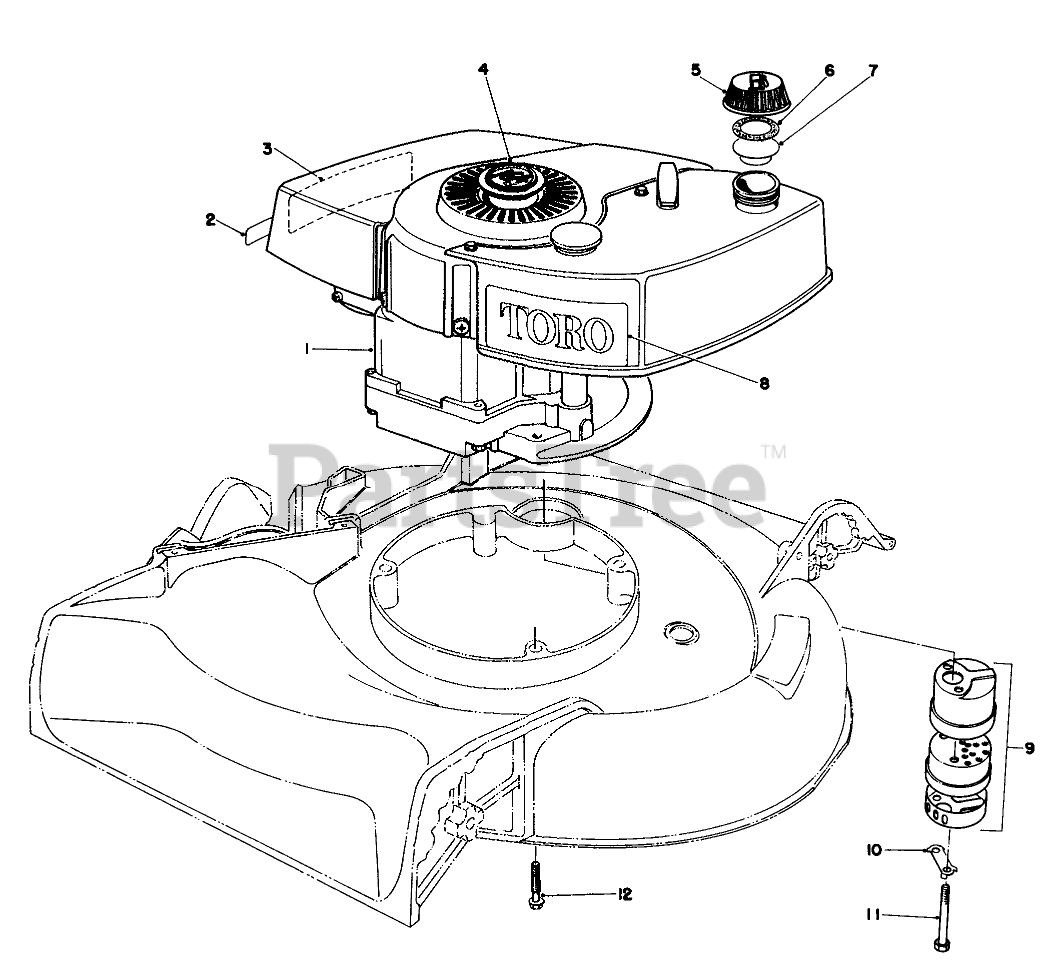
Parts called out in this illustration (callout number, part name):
1	Engine
2	Decal-Primer Bulb
3	Decal Maintenance
4	Plug Button
5	Gas Cap Assembly (Incl. Ref. #6&7)
6	144 Gasket
7	GAS CAP BAFFLE
8	Decal Toro
9	Muffler (Incl. Ref. #10 & 11)
10	CLIP - LOCKING
11	SCREW-HH
12	3/8-16 X 2-3/4 CAPSCR
